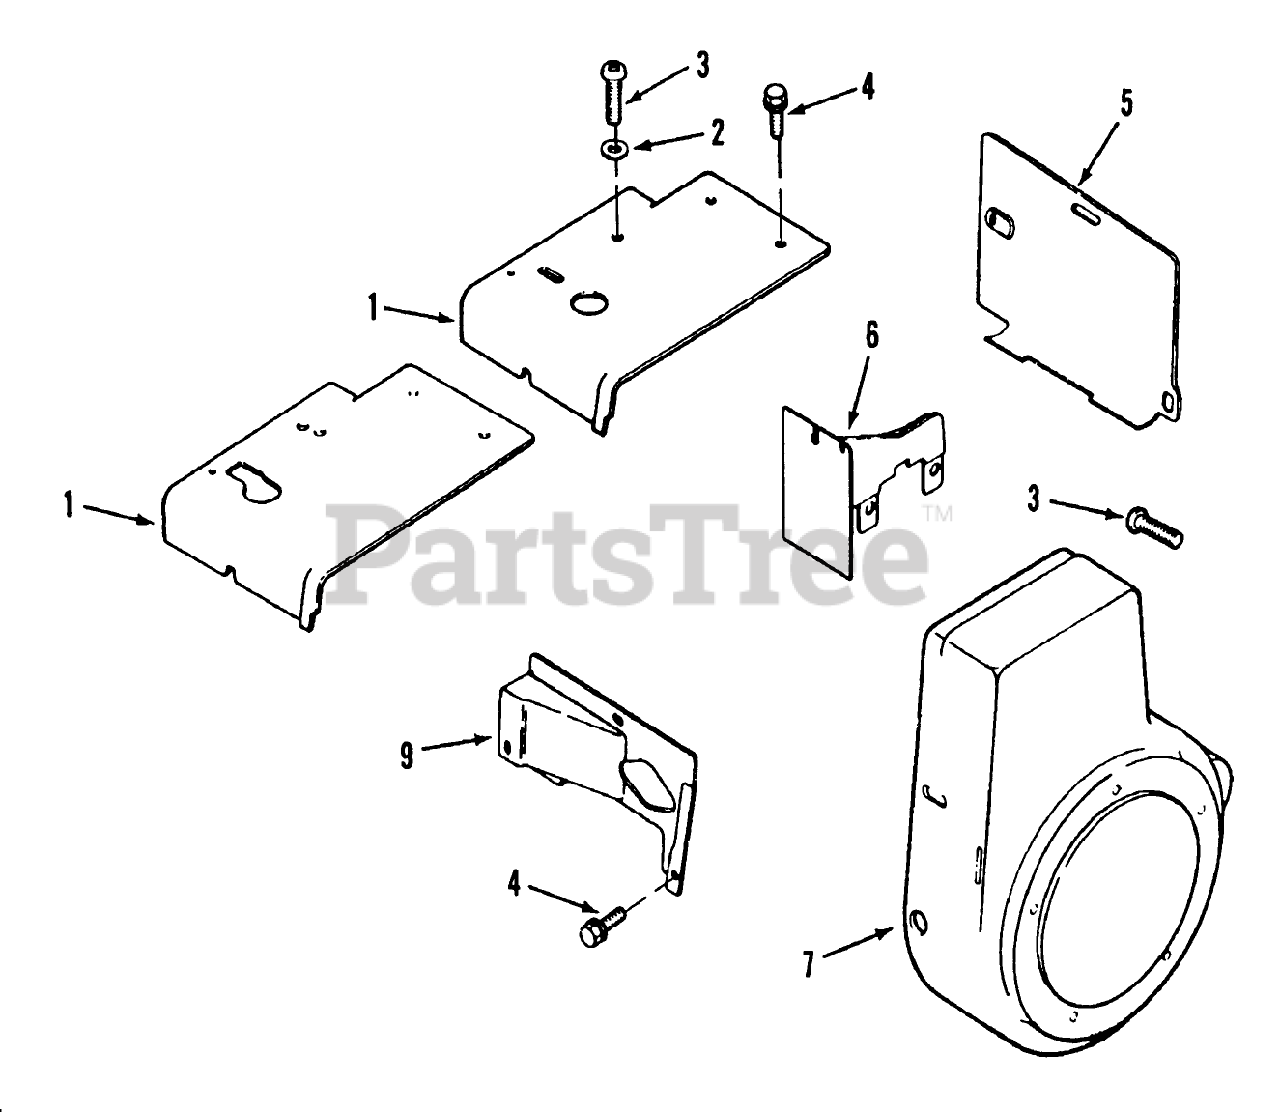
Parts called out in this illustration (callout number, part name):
1	KOHLER 47-063-09
1	KOHLER 45-063-08
2	KOHLER X-25-53
3	KOHLER 47-086-08
4	KOHLER 52-086-11
5	KOHLER 41-063-10
6	KOHLER 47-063-07
7	KOHLER 47-027-42
9	KOHLER 47-063-06
